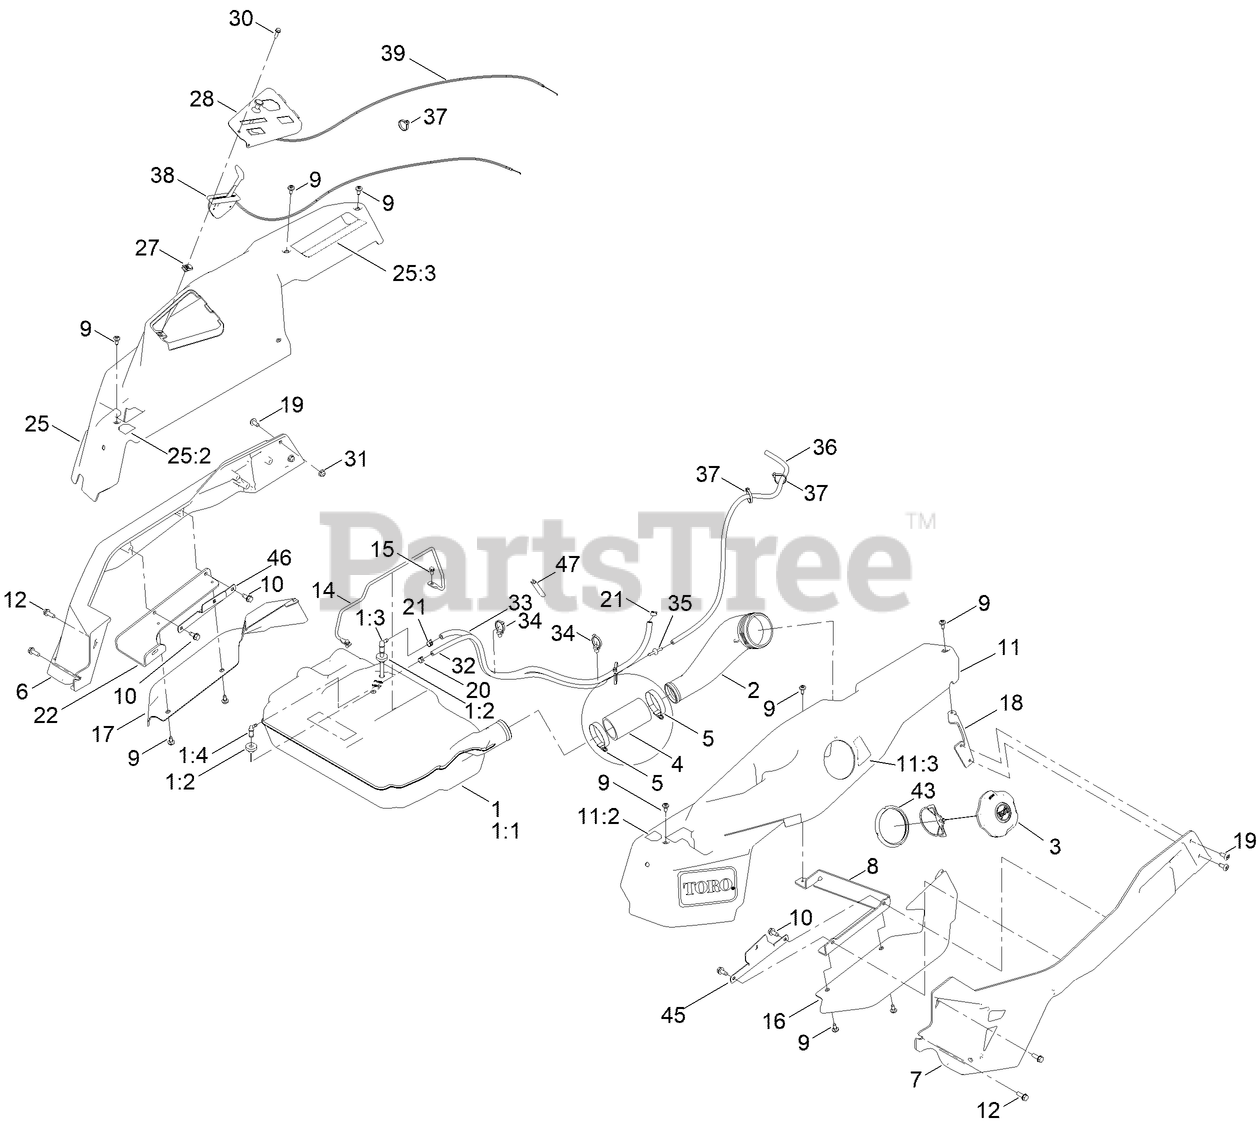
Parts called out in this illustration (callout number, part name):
1	TANK-FUEL ASM
1:1	TANK-FUEL
1:2	BUSHING
1:3	FITTING-ELBOW 90
1:4	FITTING - PICKUP, FUEL
2	NECK-FILLER, FUEL
3	CAP-FUEL, RATCHETING
4	HOSE-FILLER, FUEL
5	CLAMP-HOSE
6	CAST-TUBE, RH [RED]
7	CAST-TUBE, LH [RED]
8	MOUNT-POD BRACKET LH
9	SCREW-SHOULDER
10	SCREW-HWHTF
11	POD ASM - LH W/DECALS
11:2	DECAL-CONTROL LEVER, LH
11:3	DECAL-FUEL FILL
12	SCREW-TAPTITE
14	ROD-HOLD DOWN
15	SCREW-HWH
16	FENDER-TIME CUTTER, LH
17	FENDER-TIME CUTTER, RH
18	BRACKET-REAR POD, LH
20	CLAMP-HOSE
21	CLAMP-HOSE
22	BRACKET-MR SPRING
25	POD ASM - RH , MR W/DECALS
25:2	DECAL-CONTROL LEVER, RH
25:3	DECAL - MYRIDE
28	PANEL-CONTROL
30	SCREW-HWH
31	NUT-HF
32	HOSE-FUEL
33	HOSE-FUEL
34	CLIP-TIE
35	ADAPTER ORIFICE
36	HOSE-LP
37	TIE-CABLE
38	CABLE-THROTTLE
39	CABLE-CHOKE
43	RING-RETAINING
45	BRACKET-ALIGNMENT, POD LH
46	BRACKET- ALIGNMENT, POD RH MR
47	TRIM-EDGE GUARD
